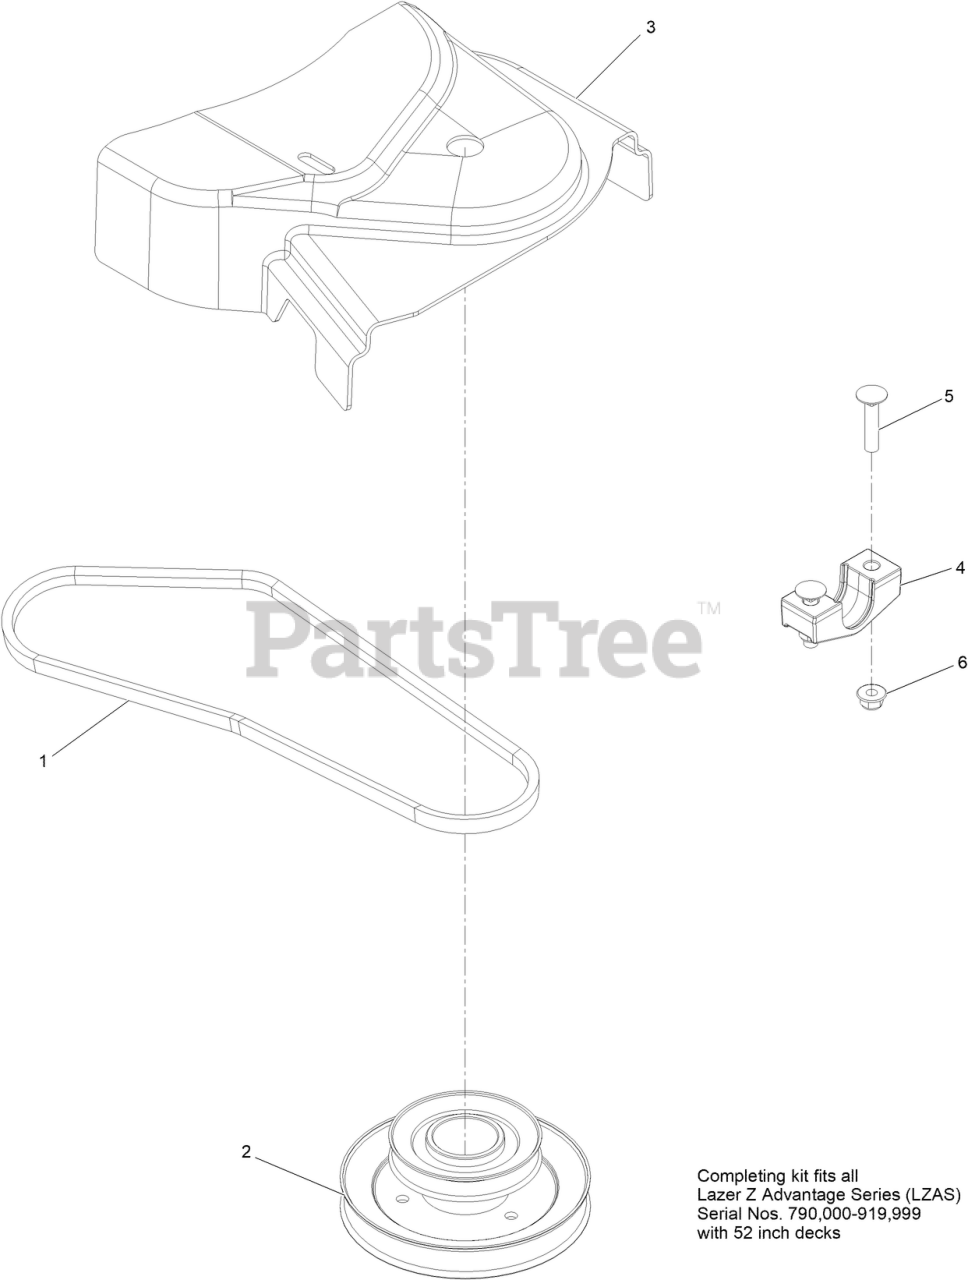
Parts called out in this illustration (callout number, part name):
2	JACKSHAFT,UV DRIVE 524
3	COVER,BELT UV 52
4	SUPPORT-BEARING CROSS SHAFT
5	SCREW-CARR
6	NUT-HF, NI
